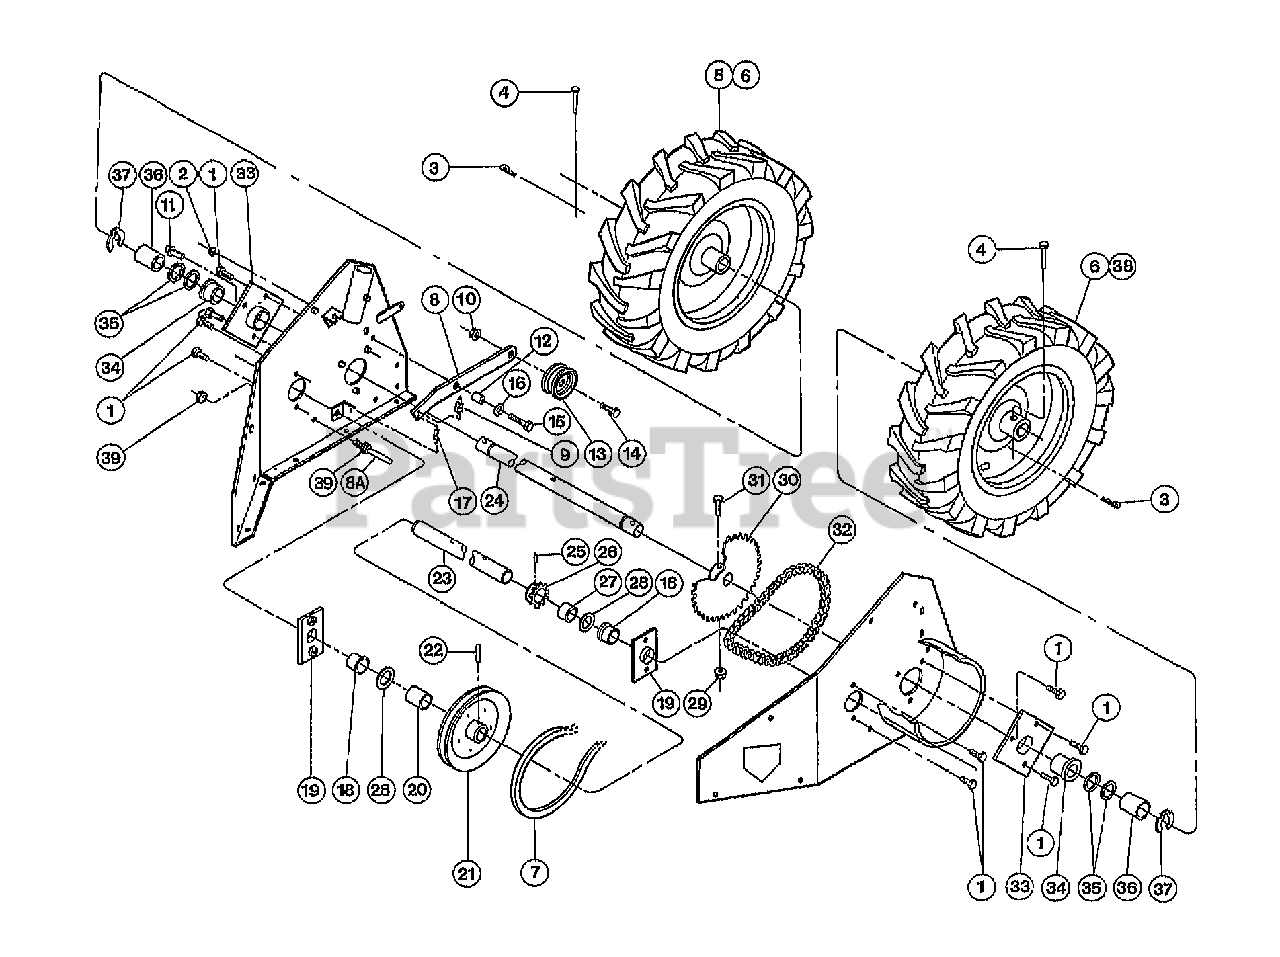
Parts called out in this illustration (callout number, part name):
1	SCR-HFLK 5/16-18X.62 G5
2	NUT-HFLK 5/16-18
3	PIN-CLIP .08
4	PIN-CLEVIS
4	PIN-QUICK RELEASE (REPLACES ITEMS 3 & 4)
5	ASSM-TIRE&WHEEL RH GRAY
6	TIRE-BTT 4.80/4.00X8.00
7	BELT-WHEEL DRIVE
8	ARM-IDLER WHEEL DRIVE
8A	PIN-BELT GUIDE
9	SPRING-CABLE
10	NUT-HFLK 3/8-16
11	SCR-HXFL 5/16-18X.5 G5
12	BUSHING-.5X.31X.843 LG
13	PULLEY-IDLER(BLADE DRIVE)
14	SCR-HFLK 3/8-16X1.50
15	SCR-HH 5/16-18X1.5 G5
16	WASHER-FLAT 5/16 SAE
17	SPRING-RETURN
18	BUSHING-FLANGE JACKSHAFT
19	PLATE-JACKSHAFT PNT. 40037P
20	SPACER-JACKSHAFT
21	PULLEY-JACKSHAFT
22	PIN-SPIROL 3/16 X 1.50
23	SHAFT-JACK MACH
24	SHAFT-WHEEL MACH
25	PIN-SPIROL .188X1.12
26	SPROCKET-9T
27	SPACER-JCKSHFT SPKT SIDE
28	WASHER-#1.25X.75X.06
29	NUT-H/LK 5/16-18 NYLOCK
30	SPROCKET-36T WELD
31	BOLT-HH 5/16-18 X 2 G5
32	CHAIN-ROLLER #41
33	PLATE-40027P
34	BUSHING/PLATE 40029/40027
35	SHIM-1.375X1.015X.062
36	SPACER-AXLE T/BLAZER
37	RING-HEAVY EXT .906 ID
38	ASSM-TIRE&WHEEL LH GRAY
39	NUT-TOP/LK 5/16-18
